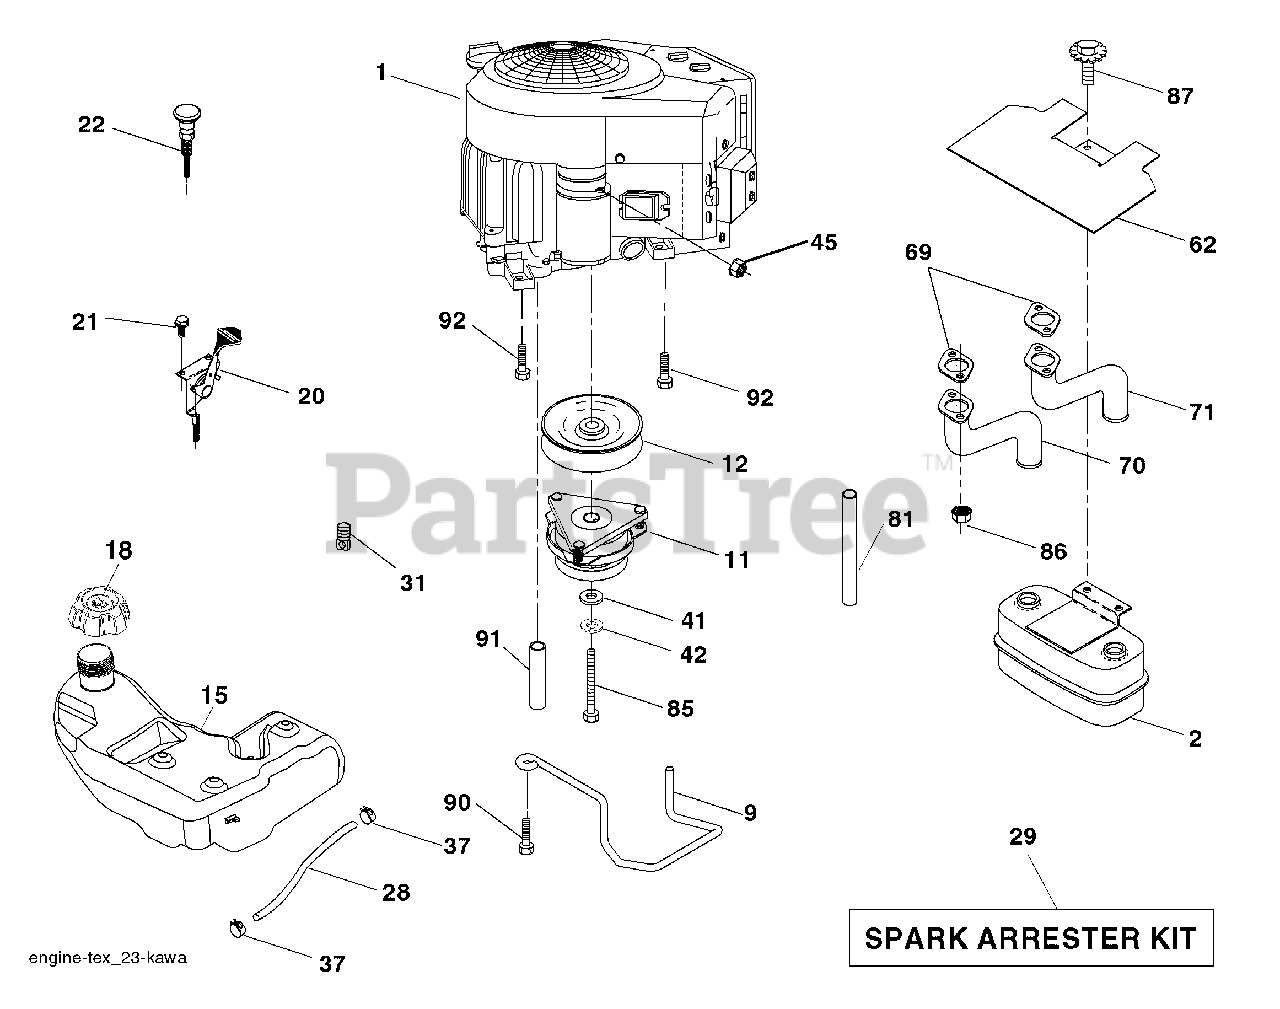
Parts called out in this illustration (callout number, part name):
9	Keeper Asm. Belt Engine
11	Clutch Electric
12	Pulley Engine
15	Tank Fuel 4.0
18	Cap Asm
20	Control Throttle
21	Screw 10 x 3/4 Single Lead Hex
22	Control Choke
28	Fuel Line
29	Spark Arrester Kit
31	Clip Push-In
37	Clamp Hose
41	Washer 1-1/2 OD x 15/32 ID x .250
42	Washer Lock 7/16
45	Nut Keps Hex 1/4-20 unc
62	Shield Heat Muffler
69	Gasket
70	Tube Exhaust LH
71	Tube Exhaust RH
81	Tube Drain Oil Easy
85	Bolt Hex 7/16-20 x 3.75 Gr. 5
86	Nut Hex Flange Toplock M8-1.25
87	Bolt 5/16-18 unc x 1 w/Sems
90	Screw 3/8-16 x 1
92	Screw 3/8-16 x 1
